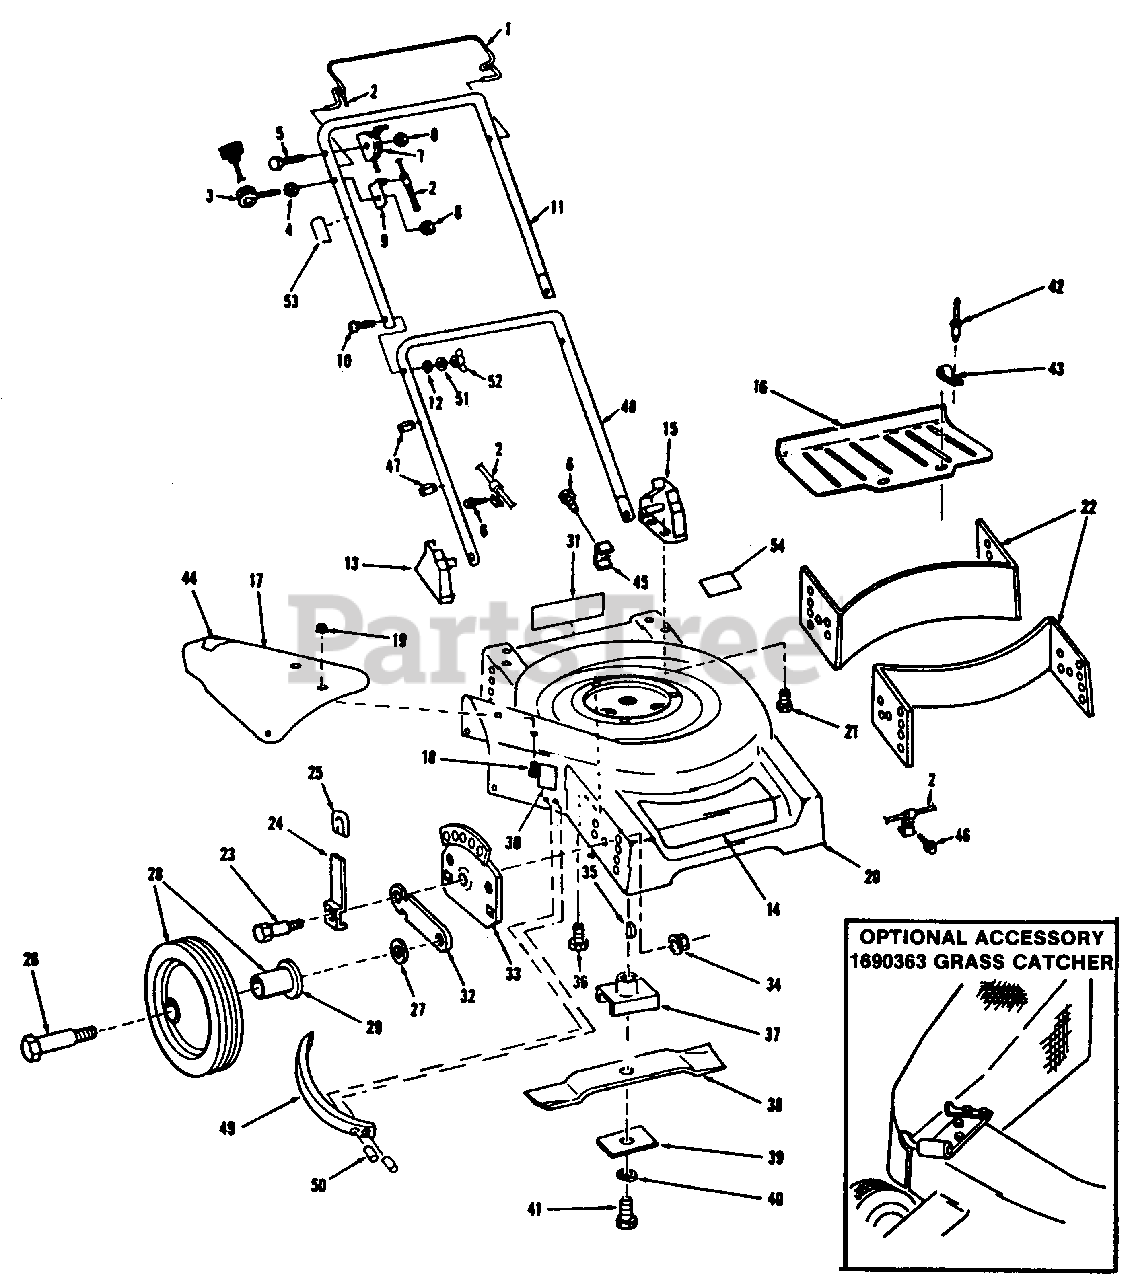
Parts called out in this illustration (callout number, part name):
1	Bail-Control
4	Nut-1/4-20
5	Bolt-1/4-20 x 1-1/2 Flex
6	Screw-Casing
7	Control-Throttle
8	Nut-1/4-20 Eslock
9	Bracket-Cable Mounting
10	Bolt-5/16-18 x 2-1/4 Curved
11	Handle-folding
12	Washer-5/16 Curved
13	Bracket Assembly-Yoke, R.H.
14	Decal-Deck, Simplicity
15	Bracket Assembly-Yoke, L.H.
16	Trailguard
17	Chute Extension
18	Bolt-Carriage
21	Bolt-1/2-20 x 1/2
23	Bolt-Shoulder Q.W.A.
24	Spring-Q.W.A.
25	Tip-Q.W.A.
26	Bolt-Axle
27	Washer-3/8 Flat
28	Wheel Assembly w/Bearing 8"
29	Bearing-Wheel
30	Decal-21"
31	Decal-Simplicity
32	Arm-Q.W.A.
33	Plate-Wheel Adj.
34	Nut-Baffle
35	Key-Engine Shaft
36	Screw-Engine
37	Blade Adapter Assembly
39	Spacer-Blade Adapter
40	Washer-Blade
42	Pop Rivet
43	Clip-Trailguard
44	Decal-Danger & Caution
45	Clamp-Casing
47	Clamp-Throttle
48	Lower Handle
49	Guard-Blade
50	Rivet-1/4" Pop
53	Decal-Engine Control
54	Decal-Starting Instructions
54	Grass Catcher
54	Replacement Bag
